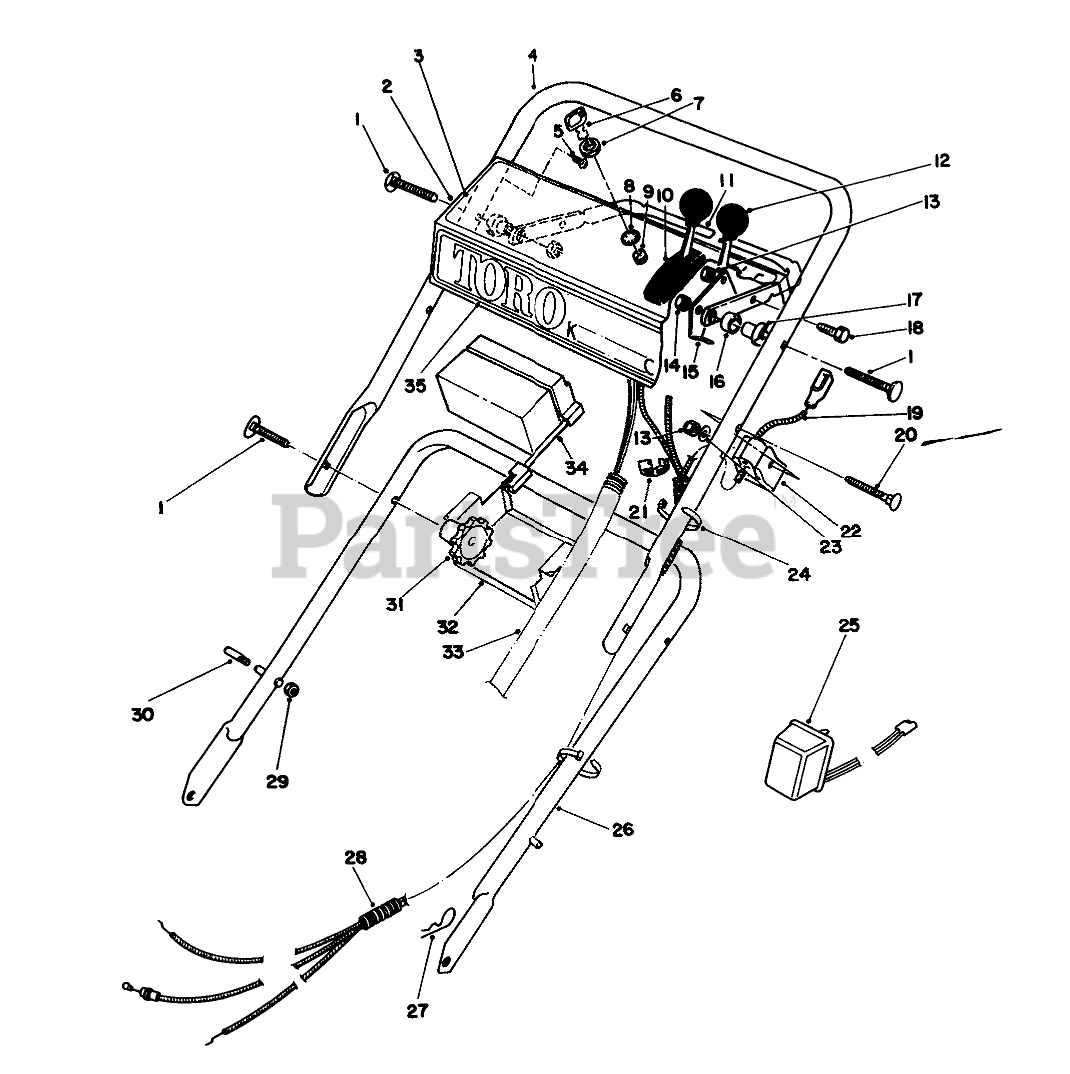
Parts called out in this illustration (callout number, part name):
1	5/16-18 X 2 HNDLE SCREW
2	Panel-Control (Incl. Ref. #3)
3	INSTRUCTION DECAL
4	UPPER HANDLE
5	SCREW-HWHTF
6	KEY-IGNITION
8	WASHER-TOOTH, INTERNAL
9	Switch-Starter (Incl. Ref. #7-8)
10	SERVICE TRACT. CONTROL
11	Bar-Control
12	SERVICE THROTTLE CONTRO
14	NUT-LOCK, NI
15	LEVER-CONTROL
16	SPACER-NYLON
17	SPACER-SUPPORT
18	SCREW-HH
19	BRAKE CABLE-SUZUKI
20	HANDLE SCREW
21	FITTING-RING
22	SUPPORT-CABLE
23	WASHER-FLAT
24	TIE-CABLE
25	Charger
26	LOWER HANDLE ASM
27	PIN-COTTER, HAIR
28	CONT. CABLE COVER
29	Locknut
30	HANDLE PIN
32	BATTERY RETAINER
33	Wire Harness Assembly
34	Battery
35	Decal-Toro
